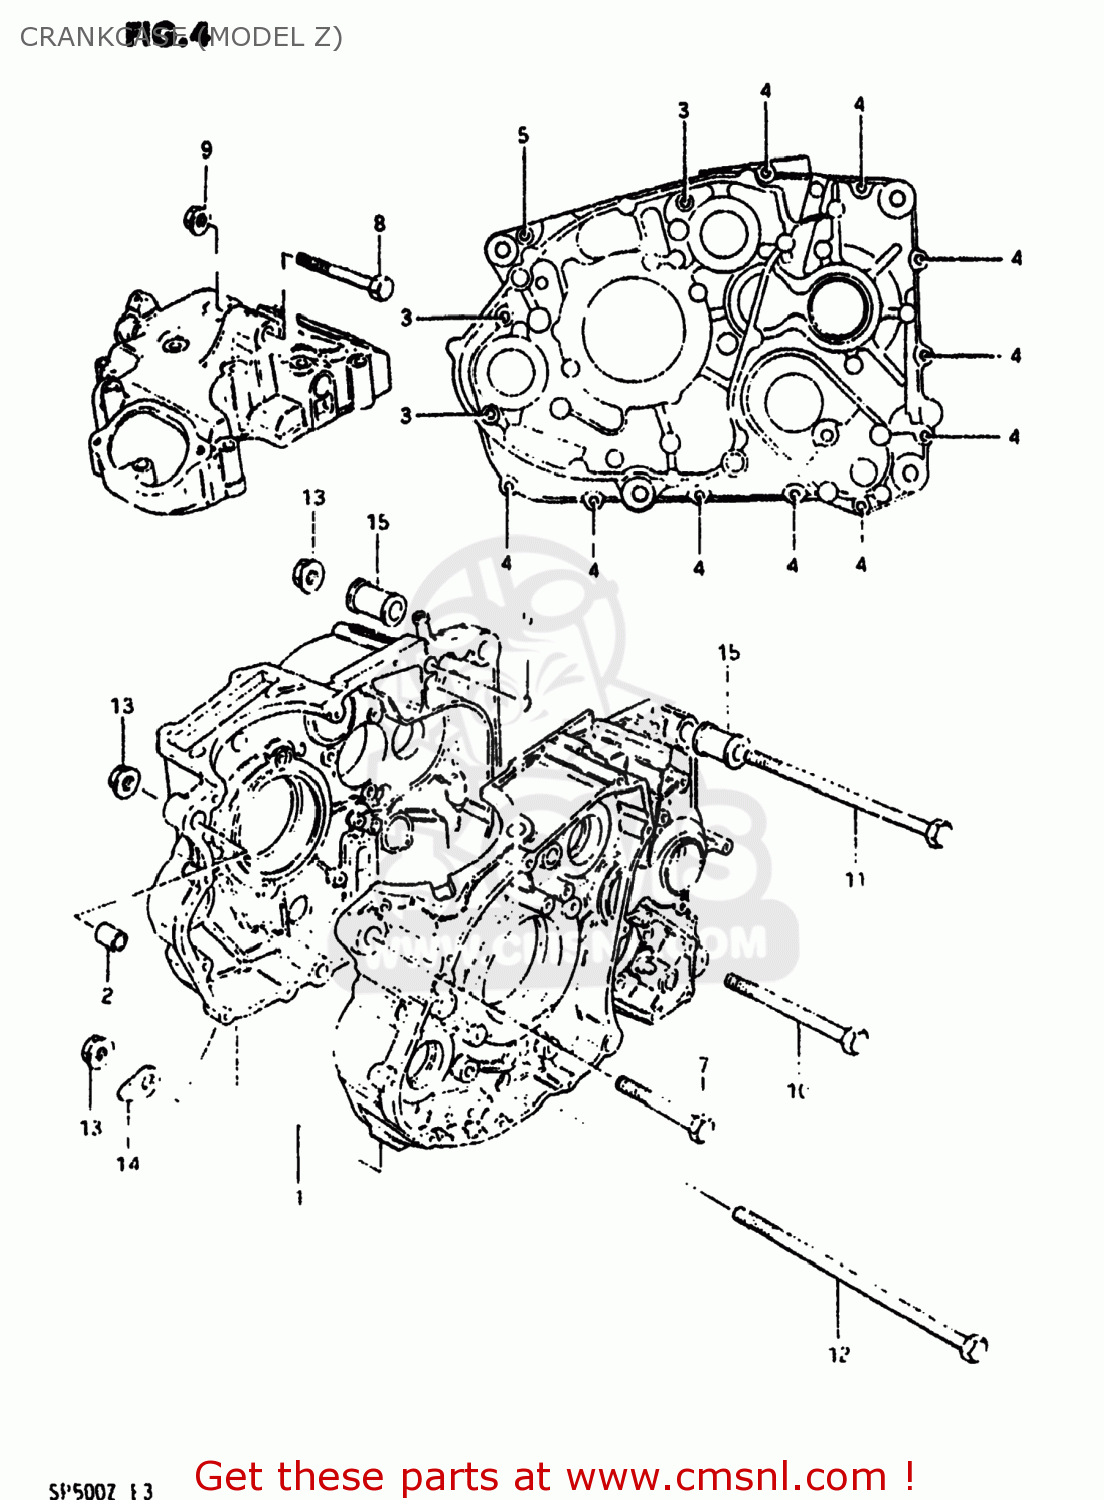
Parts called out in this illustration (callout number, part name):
1	CRANKCASE ASSEMBLY
2	PIN
3	BOLT
4	BOLT (6X40)
5	BOLT (6X30)
6	O-RING
7	BOLT(10X70)
8	BOLT
9	NUT
10	BOLT
11	BOLT
12	BOLT
13	NUT
14	WASHER
15	SPACER
